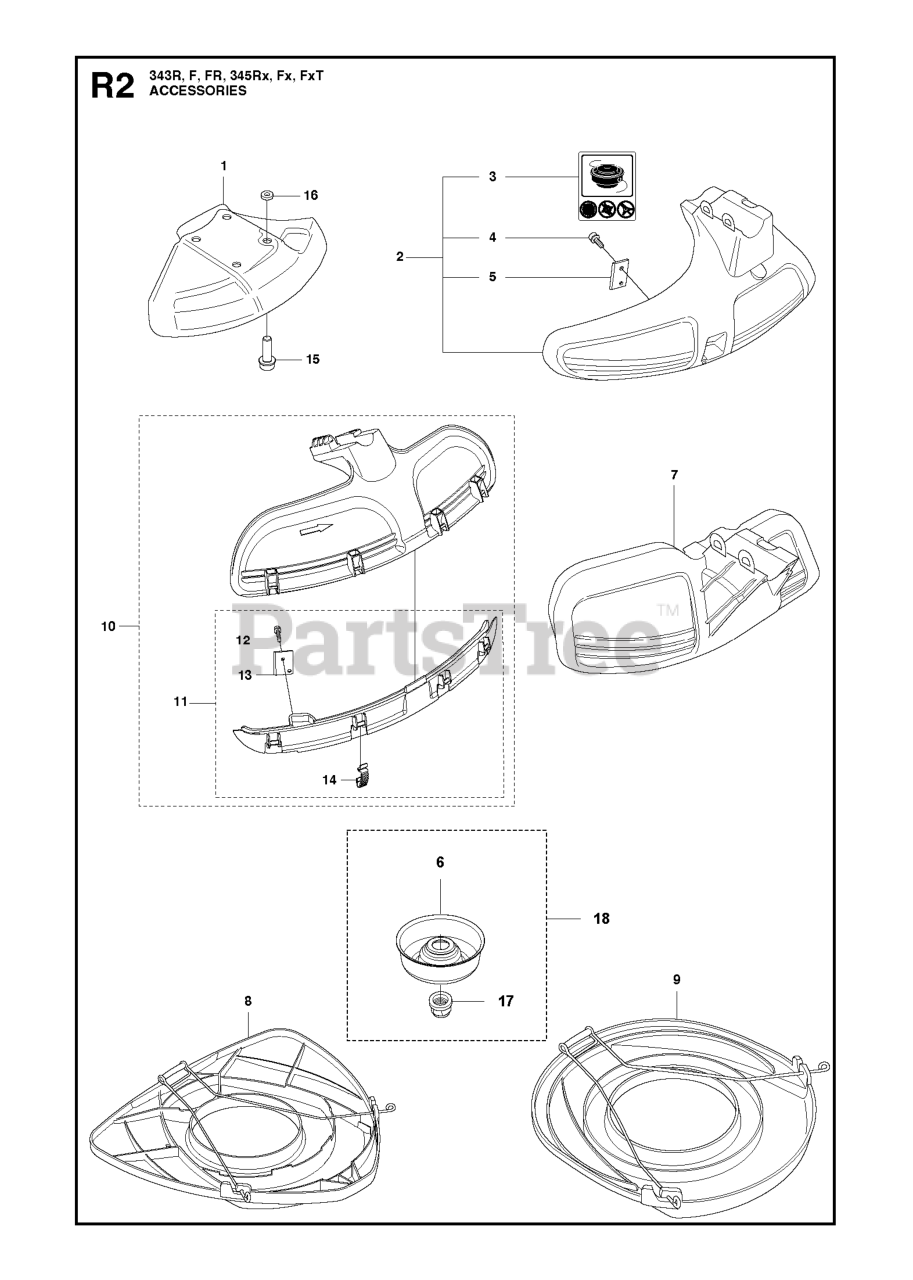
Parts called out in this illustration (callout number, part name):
1	BLADE GUARD
2	BLADE GUARD
6	SUPPORT CUP
7	BLADE GUARD
8	TRANSPORT GUARD
9	BLADE GUARD TRANSPORT
10	COMBINATION GUARD
11	SPLASH GUARD
16	LOCKING NUT
